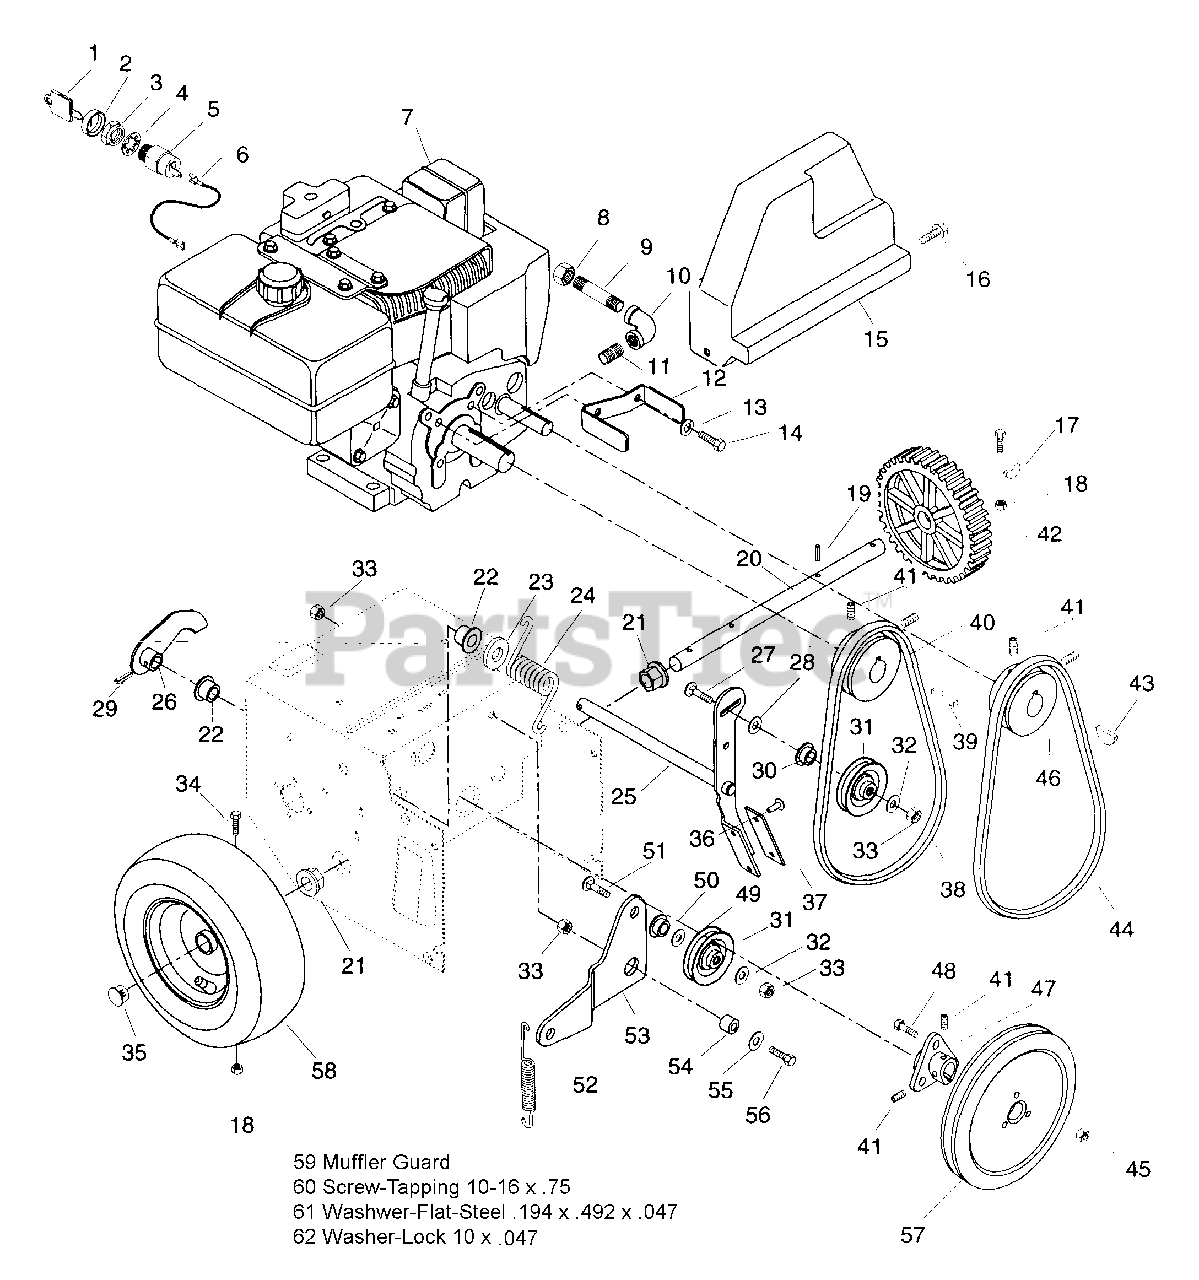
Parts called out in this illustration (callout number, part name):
1	KEY -W/CAP
2	CAP - IGNITION SWITCH
3	NUT-PANEL .625-32 GRECO
4	WSHR-LK-INT .625X.045 PL
5	SWITCH
6	WIRE
7	ENGINE-HSSK 50 TEC W/PTO
7	ENGINE 7 HP W/PTO
7	ENGINE 8HP W/PTO - TEC.
8	HEX CAP
9	NIPPLE
10	STREET ELBOW
11	NIPPLE
12	BELT FINGER
13	WSHR-LK .312X.097 PL HVY
14	BLT-HEX .31-24X.75 PL GR5
15	BELT COVER
16	SCR-TAP .250-20X.37 HWH PL TR
17	BLT-HEX .25-20X2.25 PL GR8
17	KEY-WDRF .25X.750X.313 SAE91
18	NUT-LK TOP .250-20 PL
19	PIN-ROLL .188X1.25
20	AXLE SHAFT
20	SHAFT-AXLE
21	BSHG-FLG .750X.873HEXX.53X1.18
22	BSHG-FLG.500X.625X.312X.750NY
23	WSHR-FL-STL .520X.810X.033
24	SG-TORS .148X1.0X1.53
25	CLUTCH ARM W/BRAKE PAD
26	ARM-CLUTCH
27	BLT-RDHDSQNK .31-18X1.38SHT PL
28	WSHR-FL-STL .328X.875X.062 PL
29	PIN-ROLL .156X.88
30	SPCR, BRG .315X.50X.688X.281
31	IDLER
32	WSHR-FL-STL .38X.875X.083 PL
33	NUT-LK .312-18 GR A PL
34	BLT-HEX .25-20X1.75 GR 8
35	HOLE PLUG
36	RVT-TBLR .187X.437 RH ST PL
37	BRAKE LINING
38	V-BELT, 4L-RAW EDGE
39	KEY-SQ .188X1.0X.188 SAE 8630
40	SHEAVE-ENGINE
40	SHEAVE - ENGINE
41	SCR-SET .31-18X.38 SKHCUPDL
42	GEAR
42	SPUR GEAR, FELLOWS 35T .750 ID
43	KEY-WDRF .125X.625X.250 SAE5
44	V-BELT, 3L-COGGED
44	BELT,3L 36.42 RAW LAM C-L2089
45	NUT-FLG. .312-18 PL
46	SHEAVE - CAMSHAFT
46	SHEAVE-CAMSHAFT
46	PULLEY-CAMSHAFT
48	BLT-SERRDHD SL .31-18X.75 YZ
49	WSHR-FL-STL .505X.875X.024 PL
50	BSHG, FLG .325X.499X.26X.88
51	BLT-RDHDSQNK .31-18X1.12 GR5PL
52	SG-TENS .047X.44X3.37 WLD 1.47
53	IDLER ARM
54	SPACER BUSHING .5 X .32 X .163
55	WSHR-FL-STL .344X1.375X.075 PL
56	BLT-HEX .31-18X.63 PL GR 2
57	PLY-V 8.0 X 1.25 3BLT SALEM
58	WHL-COMP 3.5 X 6
58	TIRE
58	T/WHL ASSY
